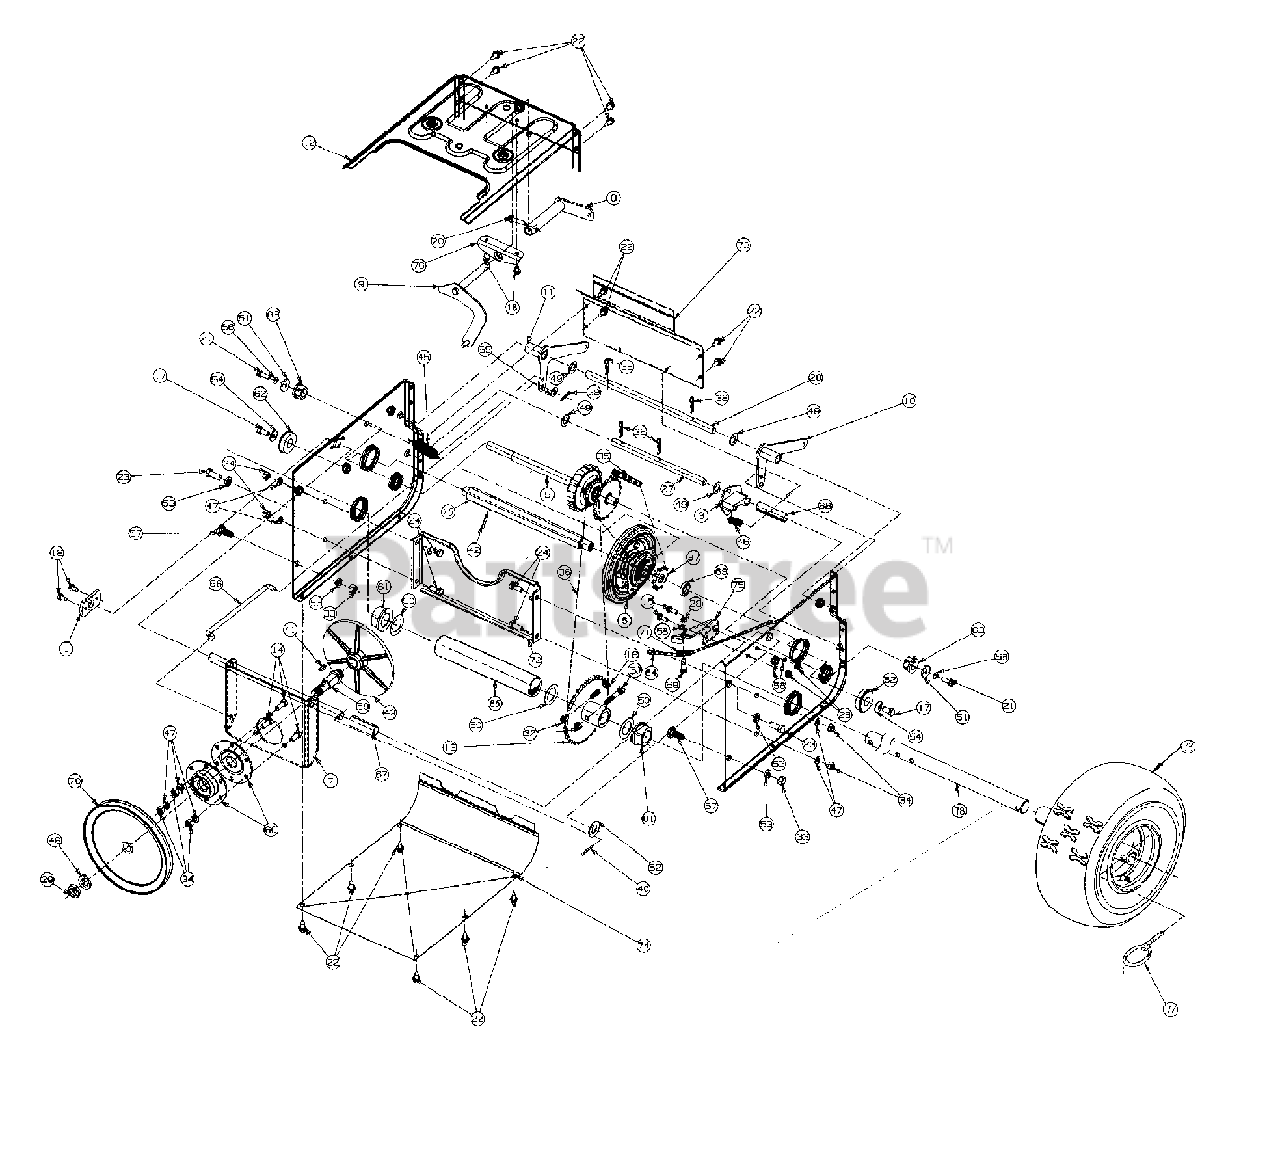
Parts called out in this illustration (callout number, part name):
1	Pivot Axle Brkt. .63 Hole - Zinc
3	Dogg Asm Dr Lh
5	Shf Asm Dr
6	Whl Asm Brg 6.0 OD Friction
10	Brkt Asm Actr Auger
14	Hex Scr 5/16-18 X .75
15	Hhcs 1/4-28 .625 Gr5 std
16	Hex Scr 5/16-18 X 1.75
17	Hhcs 5/16-18 .625 Gr5 Lock
18	Scr tt 1/4-20 .5 Hxindwsh
20	Scr Hexwash 1/4-20 X 1.25
21	Scr Tt Cl 1/4-20 .75 Hxindwsh
22	Scr Ab 1/4-14 .625 Hxindwsh
23	Hhcs 3/8-16 .880 Gr5 Std
24	Scr Cap 5/16-18 X .75 Gr 5
25	Shf Dr .875 Hex 900
26	Shf Sctr
27	Shf Actr Dr
28	Hex Nut 1/4-28
29	Hex Ins Jam L-nut 5/8-18
30	Hex Scr 5/16-18 X 2.00 Lg.
32	Hex Ins L-nut 5/16-18
33	Hex Nut 3/8-16
34	Nut Hex 5/16-18 Gd 5
35	#41 Chain 1/2 Pitch X 36 L
36	#420 Chain 1/2 Pitch X 40 L
37	Spkt 10t #41 X .500
38	Internal Cot-pin 1/2 Dia
39	Intern Cot-pin 5/16 Dia
40	Cotter Pin 1/8 Dia X 1
41	#61 Hi-pro-key 3/16 X 5/8
42	Spring Pin Roll 5/32
43	Aluminum Drive Plate
45	Idler Extension Spring
46	Extension Spring
47	Lock Washer 5/16
48	Lock Washer 5/8
49	Wash Fl .531 ID X .930 OD X .05
50	Wash Fl 1.03 ID X 1.62 OD
51	Wash Flt 1/4 ID X .930 OD X .12
52	Wash Flt .640 ID X 1.24 OD X .06
53	Lock Washer 3/8 Heavy
54	Bell Wash .345 ID X .88 OD
55	Fl-wash Sae .34 X .68 .062
56	Lock Washer 1/4
57	Shld Scr .498 Dia X .340
58	Drive Plate Spindle
59	Scr Shldr .340 D. 1/4 Ab
60	Asm Brg Hsg
61	Flange Brg Pm W/flts 1.0
62	Ball Bearing W/snap Ring
63	Brg Hex Flange X .564 ID
64	Cb Idlr Auger
65	Spcr 1.017 ID X 7.80 Lg.
66	Rod Clu Dr
67	Spcr Splt .64 X .77 X 2.1
68	Split Spacer 1/2 X 5/8 X 2.44
69	Spcr .675 ID X 1.00 OD X .23
70	1/2 V-pulley .62 ID X 7.5
71	Cable Guide Roller
77	Klick Pin Ass'y
78	Axle 1.0 OD X 28.35 Lg
